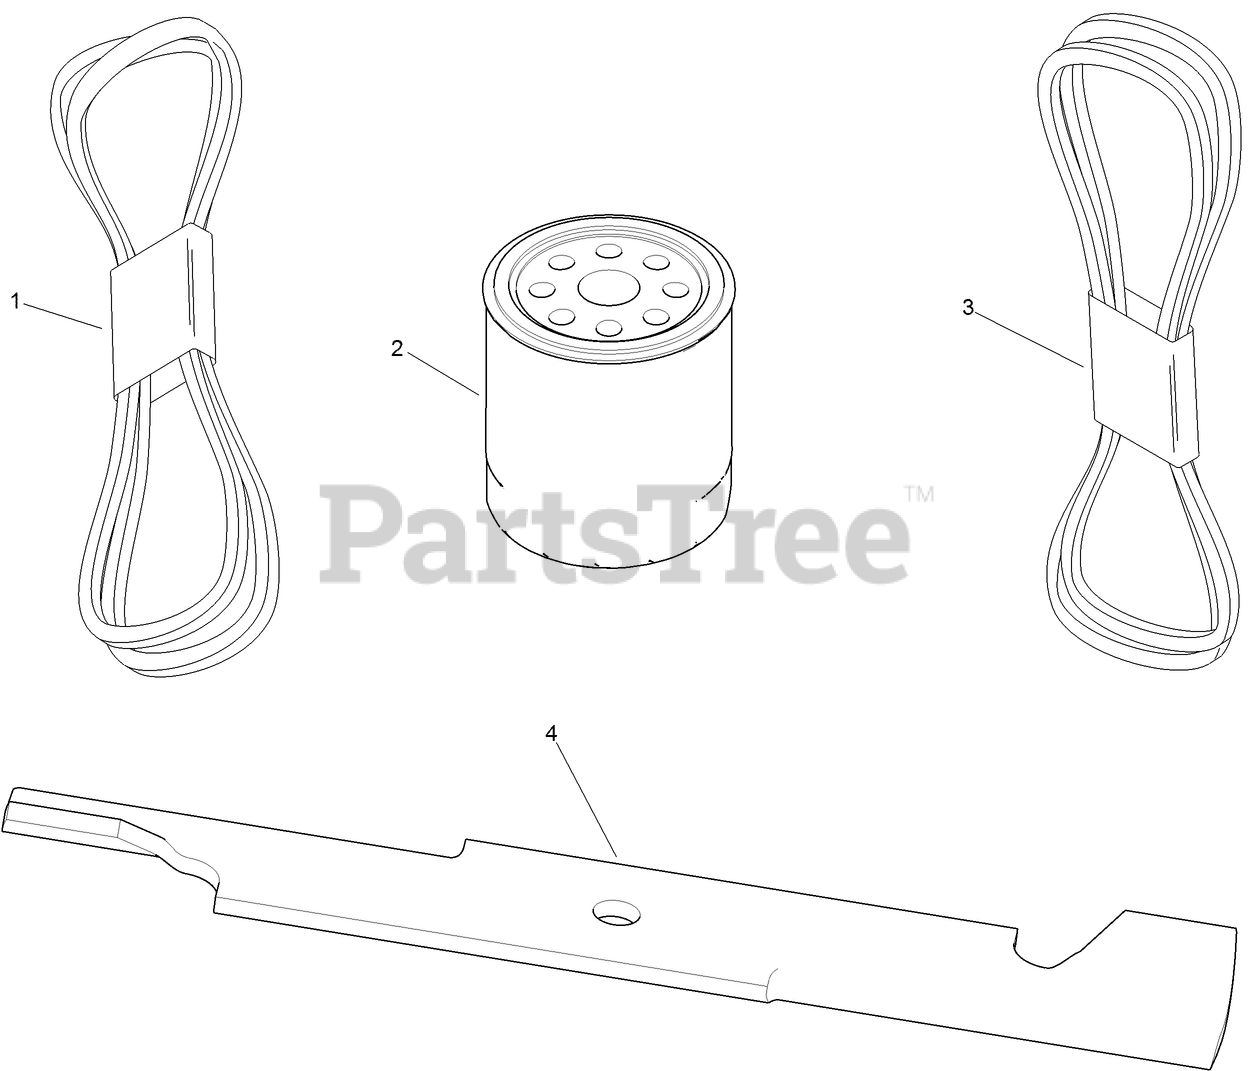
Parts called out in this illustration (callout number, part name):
1	BELT-V, LOWER PTO
2	ELEMENT-FILTER, 25 MICRON
3	BELT-V
4	BLADE-16.5 INCH (HIGH FLOW)
